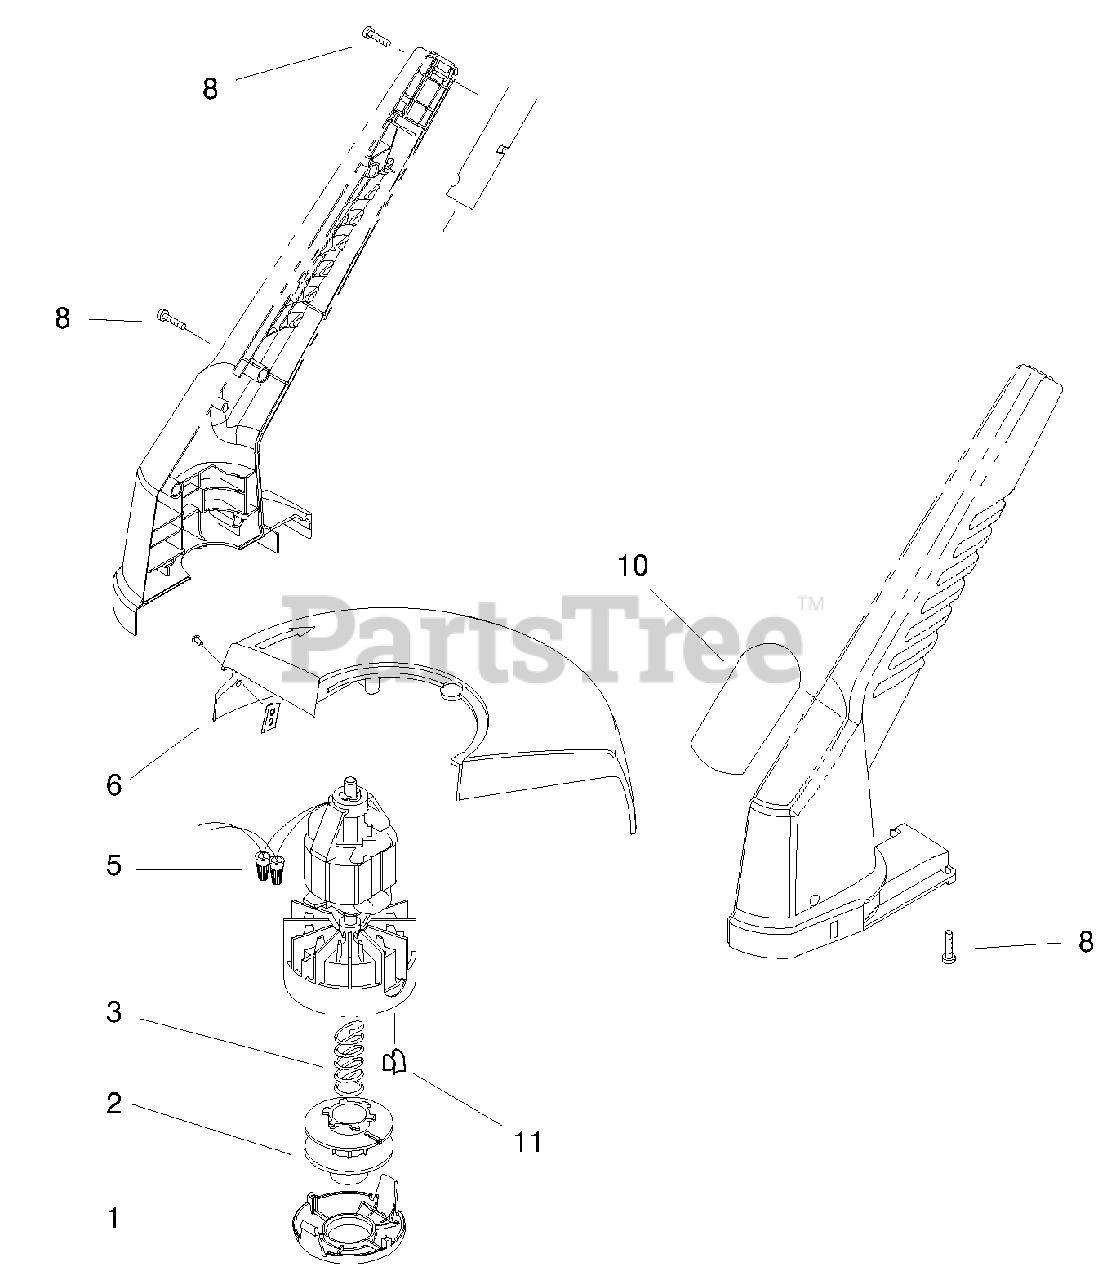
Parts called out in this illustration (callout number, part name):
2	Spool-Large
3	Spring-Compression
5	Connector-Wire Nut
6	Shield ASM
8	Screw-PPH
10	Decal-14" Trim 'n Edge
